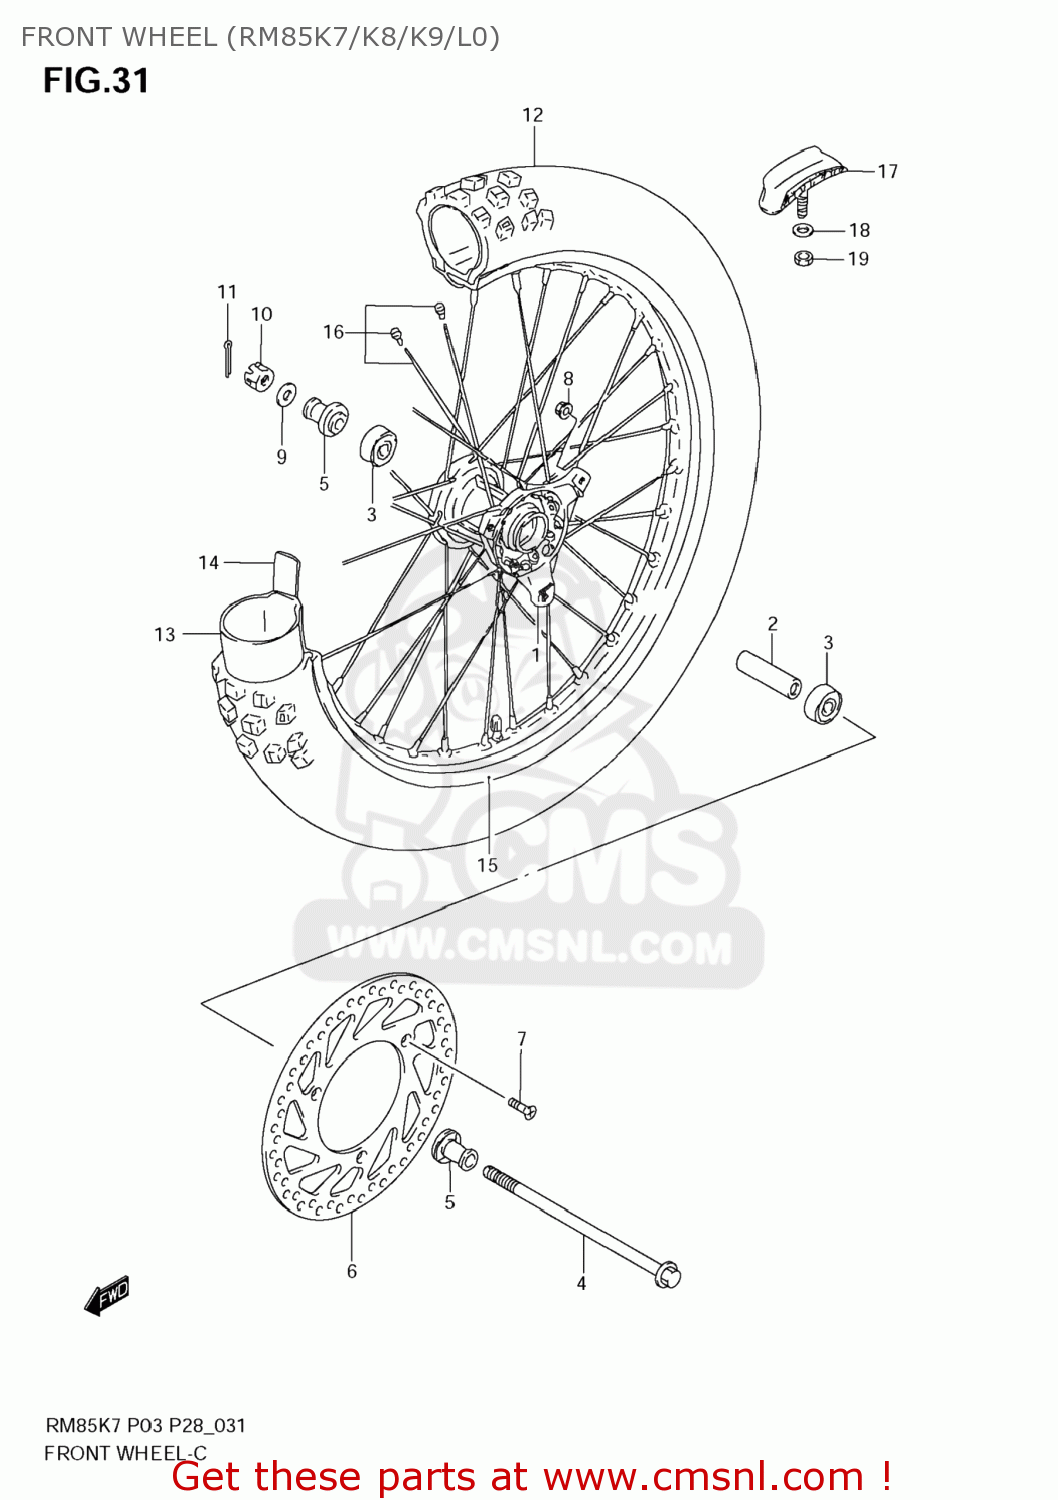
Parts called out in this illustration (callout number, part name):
1	HUB,FR WHEEL
2	SPACER,FR HUB BEARING
3	BEARING (12X32X10)
4	AXLE,FR
5	SPACER,FR AXLE
6	DISC,FR BRAKE
7	SCREW(6X22)
8	NUT
9	WASHER
10	NUT
11	PIN
12	TIRE,FR(70/100 17)
13	TUBE ASSY,WHEEL INNER
14	PROTECTOR,WHL INR TUBE
15	RIM,FR WHEEL(17X1.40)
16	SPOKE SET,FR WHEEL
17	STOPPER,BEAD
18	WASHER
19	NUT
